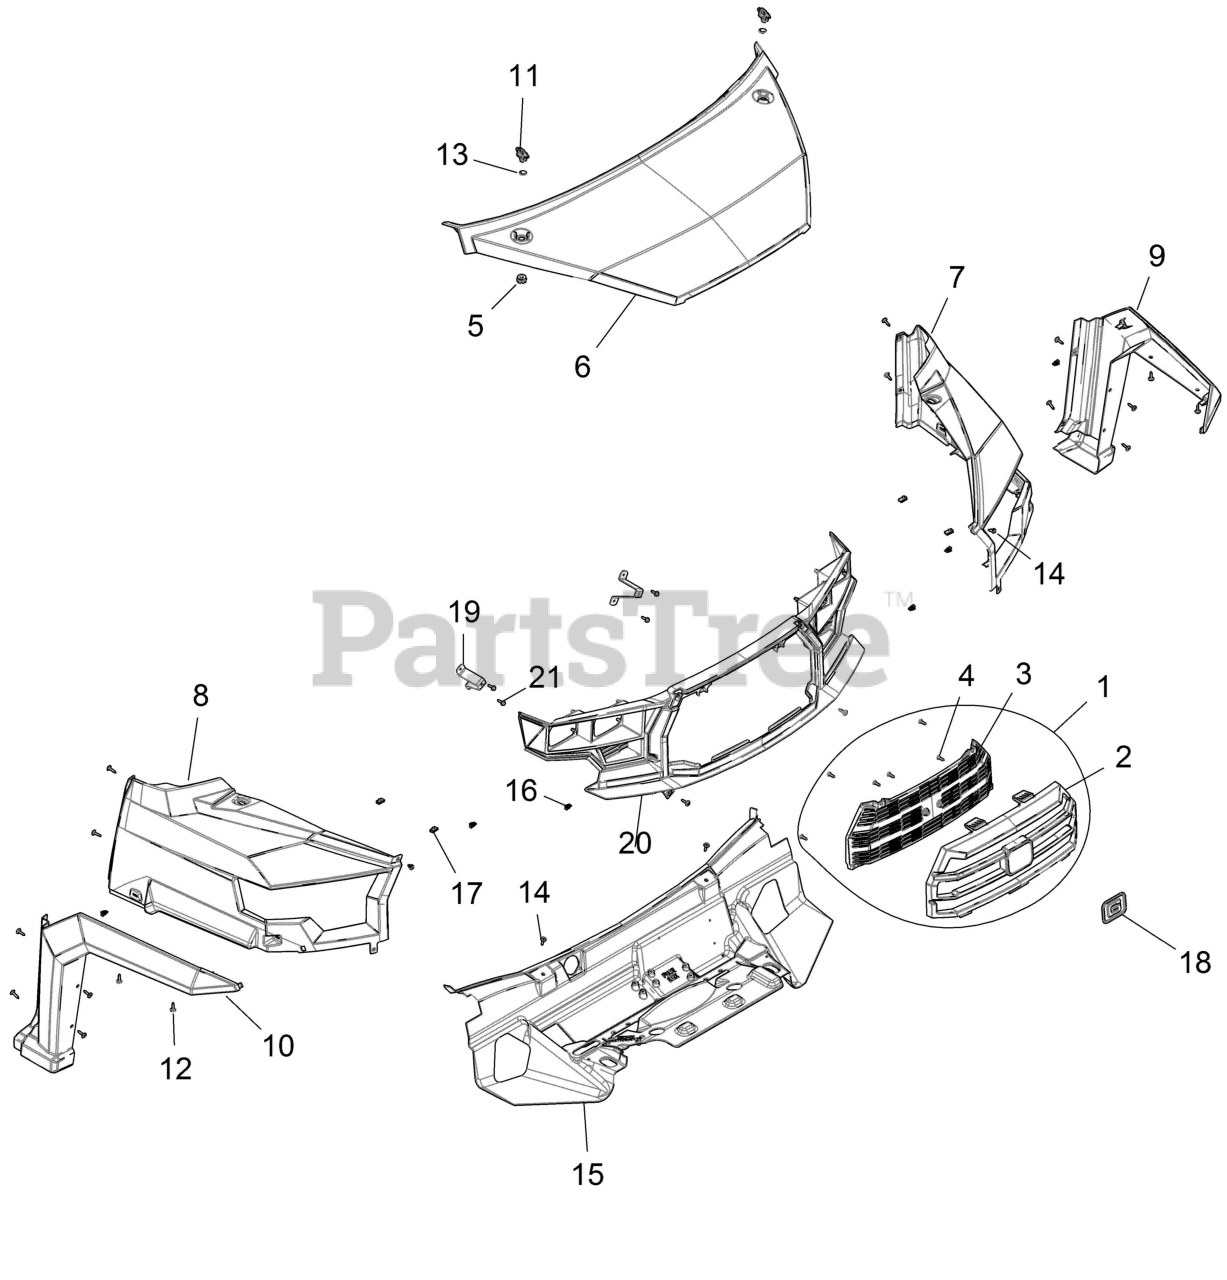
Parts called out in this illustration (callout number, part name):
1	ASM., GRILL, GRAVELY
2	GRILL, FRONT, UPPER, BLACK
3	GRILL, UPPER, TRIM
4	SCR-TXPH-#14 X .75 HI-LO RIE
5	GROMMET-LATCH
6	HOOD-ARIENS,INDY RED
7	FENDER-FRONT,LH,ARIENS,I RED
8	FENDER-FRONT,RH,ARIENS,I RED
9	FLARE, FENDER, FRONT LH
10	FLARE, FENDER, FRONT RH
11	LATCH, 1/4 TURN
12	SCR-TXTH-M6X1.0X25 RIE
14	RIVET-TUFLOK,.315-.325X.787 (5
15	LINER-HOOD,BLK
16	CLIP, DASH TRIM METAL
17	CLIP-U SPEED NUT
19	BRKT-FASCIA MOUNT
20	BEZEL-HEADLIGHT
21	SCR-M6X1.0X20,HXHD,FLG,TDFM,BL
